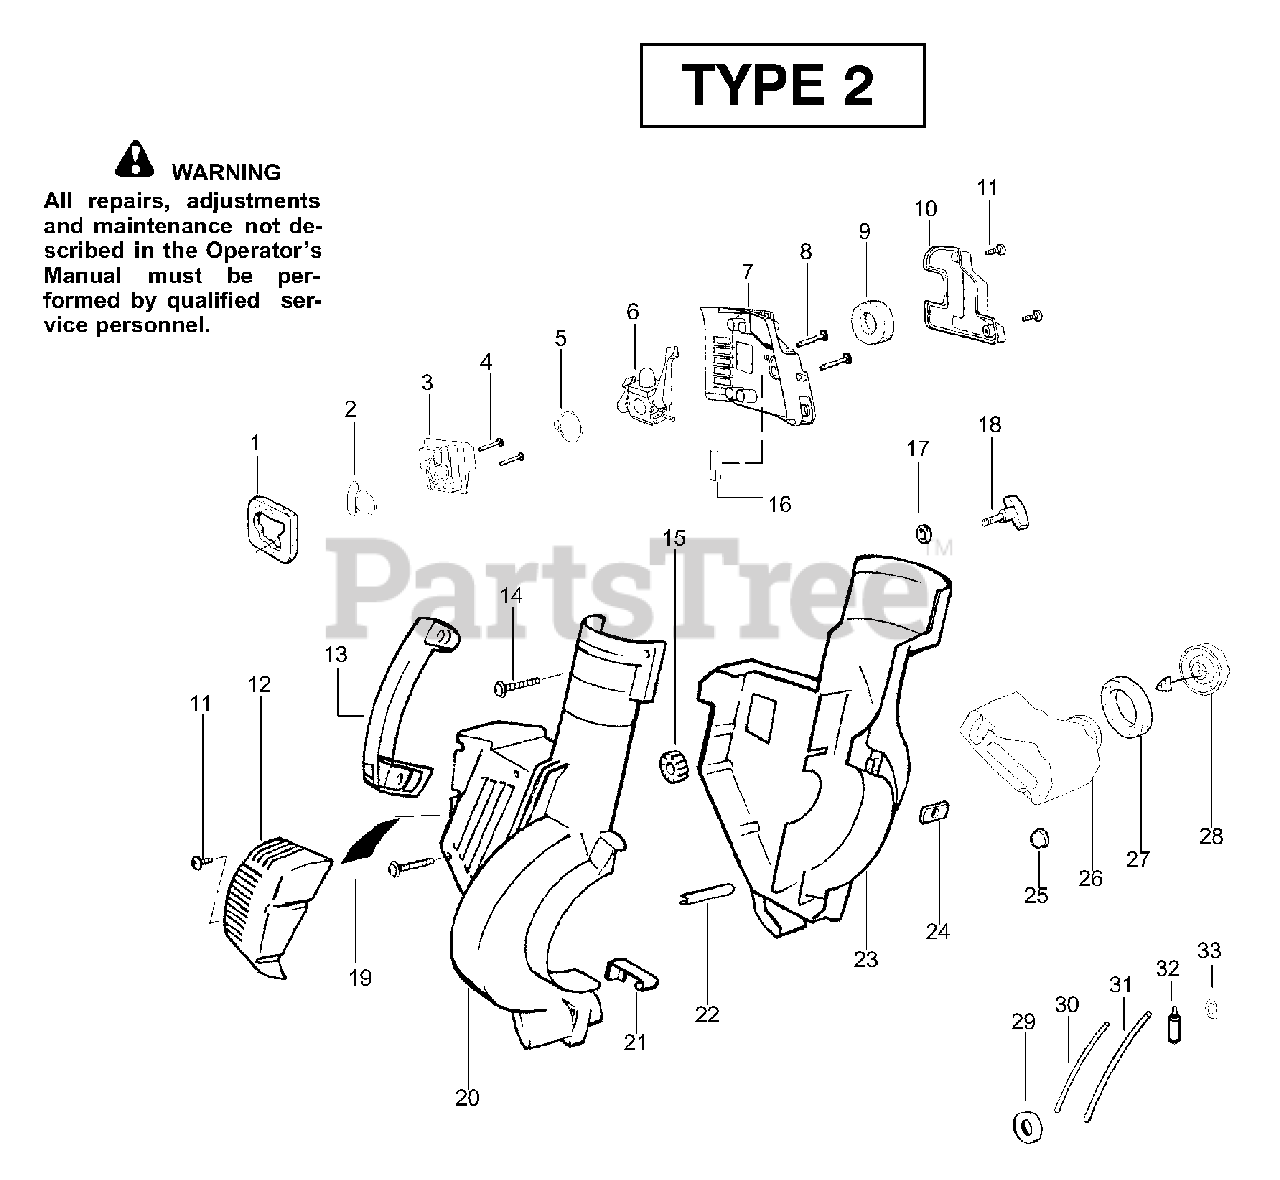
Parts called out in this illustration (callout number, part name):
1	Air Dam (kit)
2	Gasket-Adapter (kit)
3	Carburetor Adaptor
5	Gasket-Carburetor (kit)
6	Kit Carb Ass'y (C1Q-W11)
6	Kit Carb Ass'y (C1Q-W11C)
8	Screw-Carb.
9	Filter-Air
10	Cover-Air Filter
12	Guard-Muffler
15	Isolator
16	Foam 25.4mm (kit)
18	Knob-Tube Clamp
19	Reflector-Heat (kit)
20	Housing-Right
21	Spring-Cover Latch
22	Guide-Starter Rope
23	Housing-Left
25	Isolator-Crankcase
26	Assy-Fuel Tank
27	Gasket-Fuel Tank
28	Fuel Cap w/Retainer
29	Grommet-Shroud
30	Kit-Line Carb/Purge
31	Kit-Line Tank/Purge
32	Assy-Fuel Pick-up
33	Grommet-Fuel line (kit)
